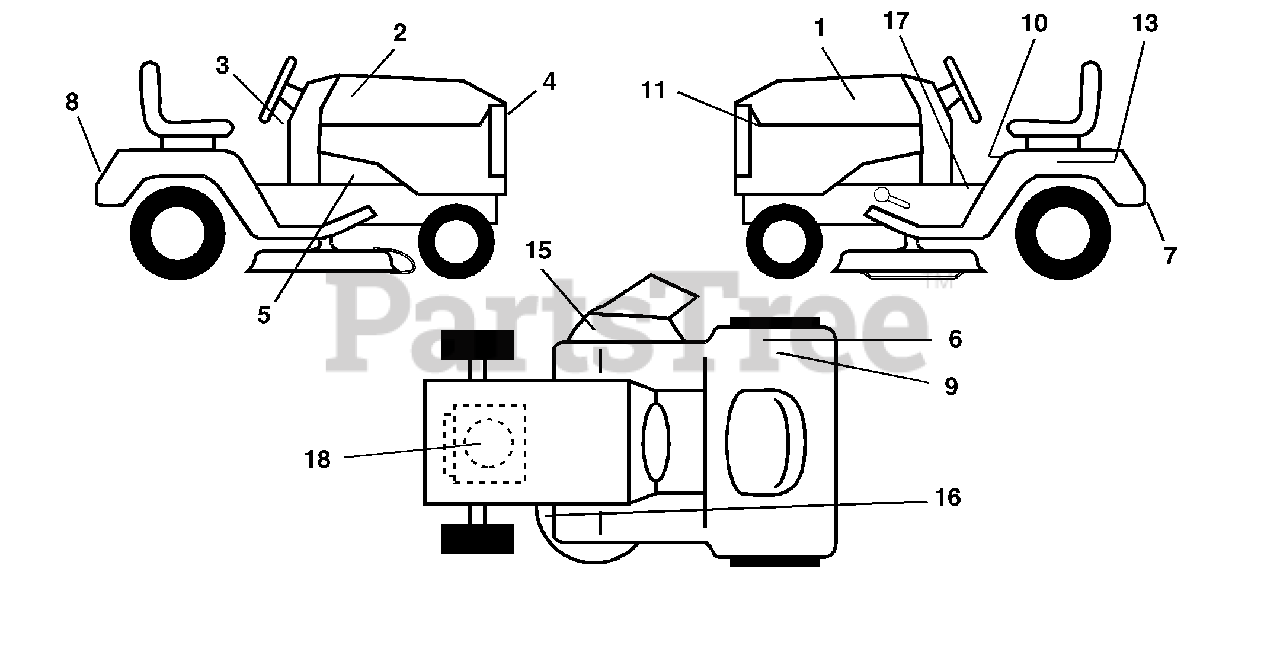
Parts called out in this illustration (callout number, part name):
1	Decal, Hood, L. H., Husqv.
2	Decal, Hood, R. H., Husqv.
3	Decal, Dba
4	Decal, Grille Husq.
5	Decal, Chasis Hot Muffler
6	Decal Europe Stand. CE Tractors
7	Decal, Drawbar, Load Limit
8	Decal, Logo, Fender
10	Decal, Read Owner's Manual Symbols
11	Decal, Pnl Side, B&S Husq.
13	Decal, Battery
15	Decal, Cutfinger
16	Decal, V-Belt Sch.
17	Decal, Brake/Clutch Symbols
18	Decal, Engine
